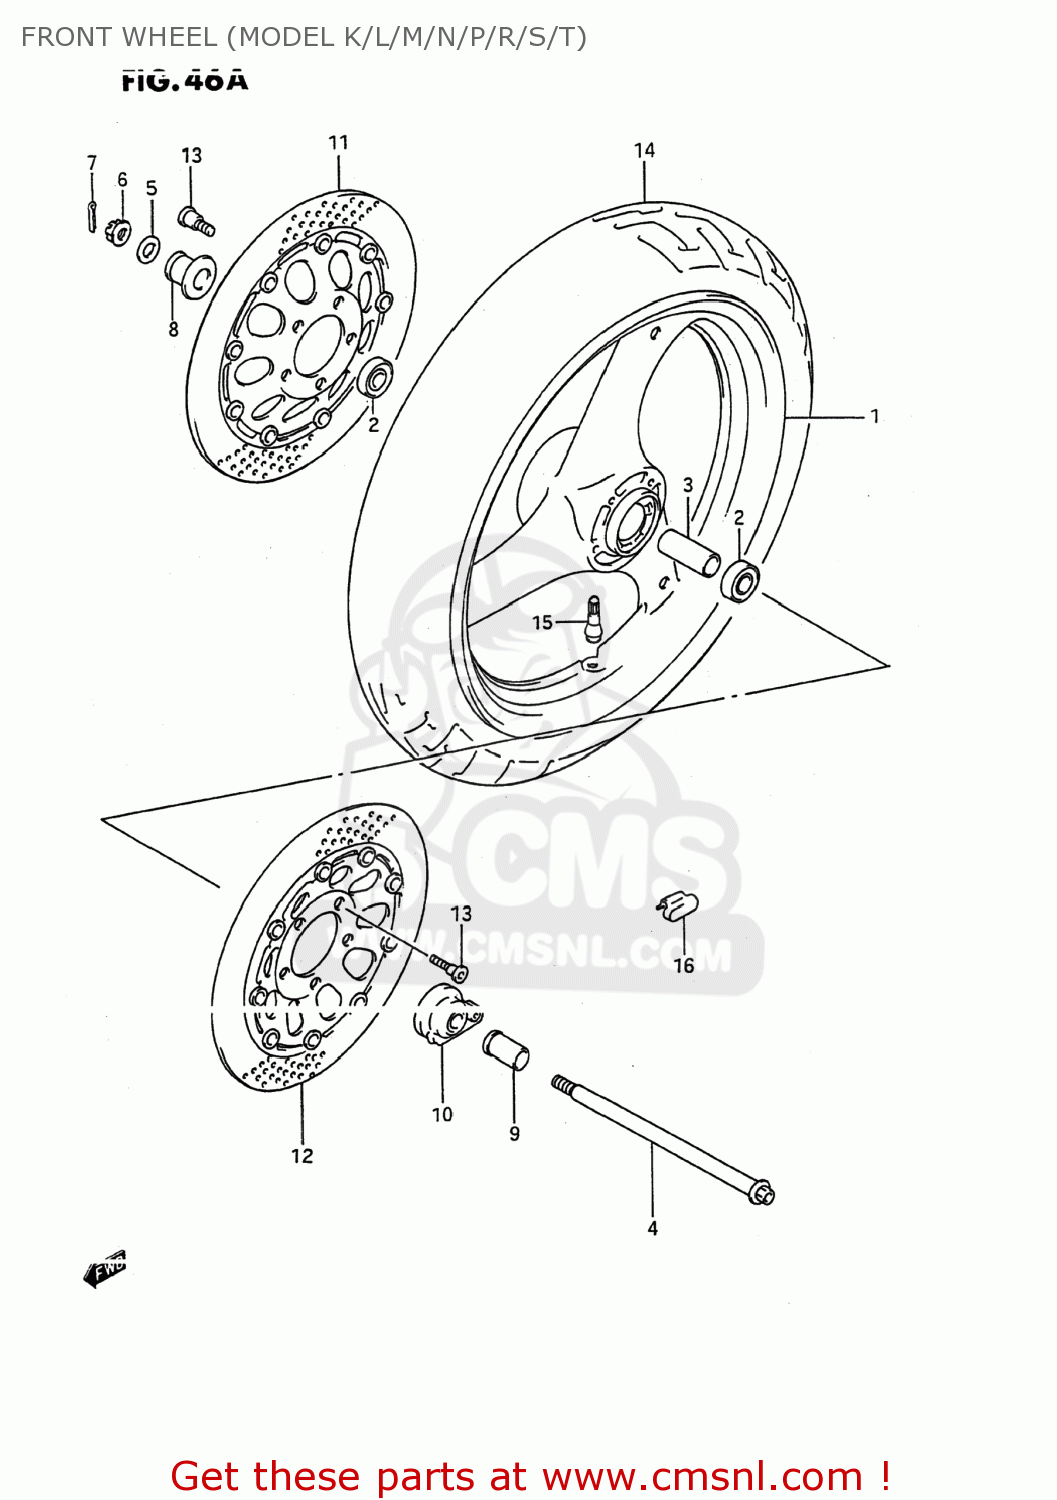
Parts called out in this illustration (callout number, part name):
1	WHEEL,FRONT (MT3.00X17)
2	BEARING
3	SPACER(15.3X21.7X63)
4	AXLE,FR
5	WASHER
6	NUT
7	COTTER PIN
8	SPACER,FR AXLE
9	SPACER,FR AXLE,L
10	BOX ASSEMBLY,SPEEDOMETER GEAR
11	DISC,BRAKE
12	DISC,BRAKE
13	BOLT 8X33
14	TIRE,FRONT 110/80-17.5
15	VALVE,TIRE
16	BALANCER,WHEEL
